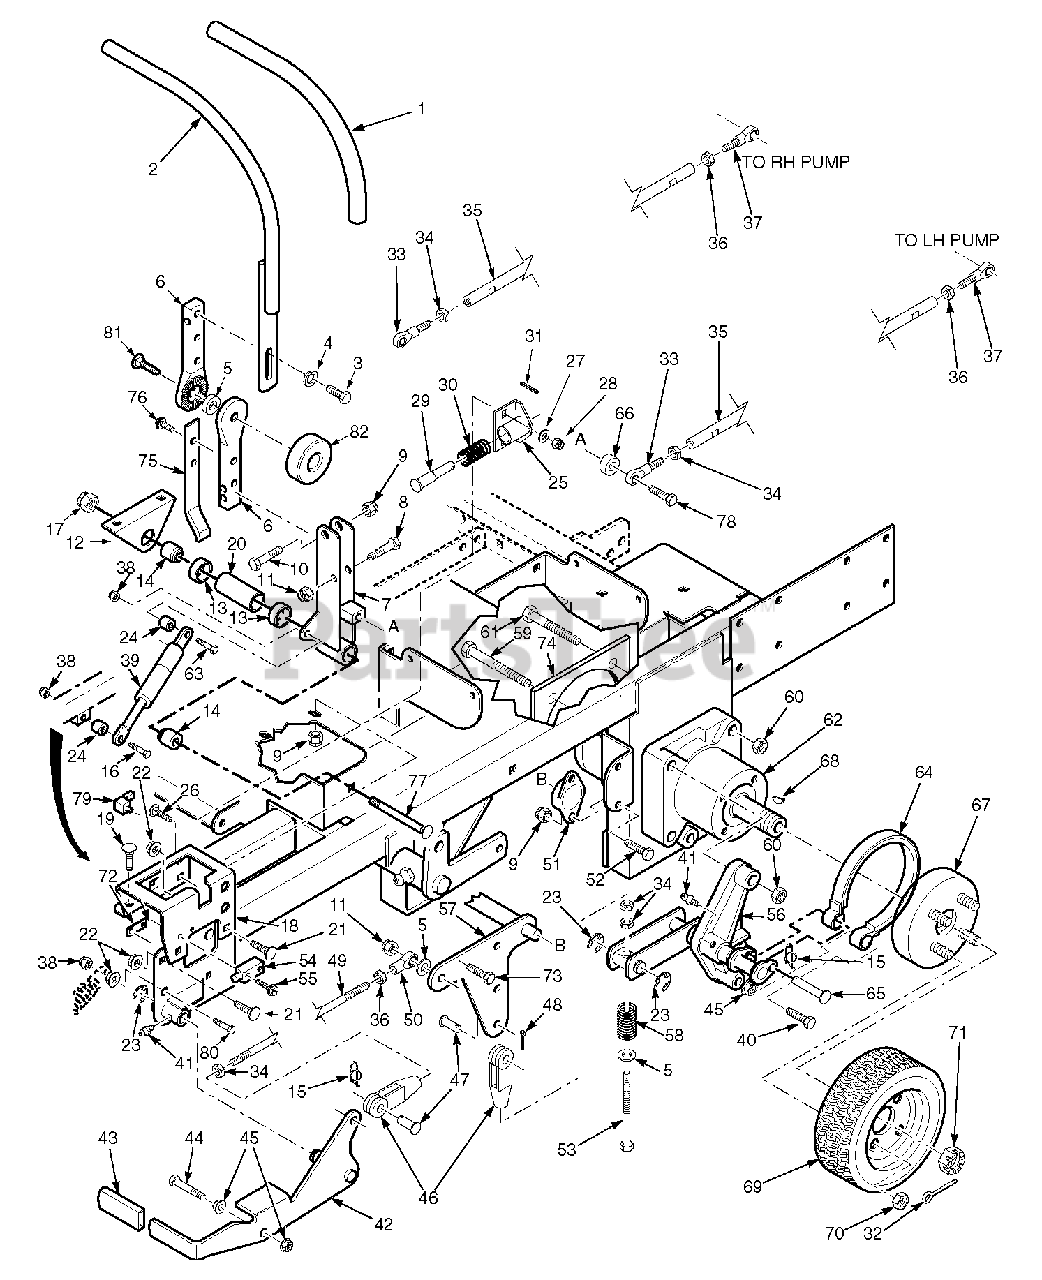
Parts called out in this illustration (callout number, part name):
1	Grip, Handle Bar
2	Handle Bar, LH
2	Handle Bar, RH
3	Bolt, Hex Head 5/16-18 x 1"
4	Lockwasher, 5/16"
5	Rubber Spacer
6	Bar, Control Lever
7	Control Lever Weldment, LH
7	Control Lever Weldment, RH
8	Bolt, Hex Head 5/16-18 x 2"
9	Nut, Hex Elastic Stop 5/16-18
10	Bolt, Hex Head 3/8-16 x 2"
11	Nut, Hex Elastic Stop
12	Mount, Control Linkage
13	Ball Bearings, Neutral Return
14	Spacer
15	Pin, Rue Cotter 3/8" Dia.
16	Bolt, Hex Head, 5/16-18 x 2.75" Zinc
17	Nut, Hex Elastic Stop 5/8-11
18	Bracket, Control Lever LH
18	Bracket, Control Lever RH
19	Bolt, Carriage 5/16-18 x 1"
20	Spacer, Bearing
21	Bolt, Carriage 5/16-18 x 3/4"
22	Nut, Hex Serrated Flange 5/16-18
23	Ring, Retaining 5/8" External "E"
24	Spacer
25	Bracket, Neutral Return
26	Bolt, Carriage 1/4-20 x 3/4"
27	Flatwasher, 1/4" (.312 x .750 x .065")
28	Nut, Hex Elastic Stop 1/4-20
29	Pin, Retaining Spring
30	Spring
31	Roll Pin, Spring 5/32" x 3/4"
32	Pin, Cotter 9/16" x 1-1/2"
33	Rod End, Male 3/8"-24 RH Thread
34	Nut, 3/8"-24 RH Thread
35	Tube, Control Link Air-Cooled Engine
35	Tube, Control Link Liquid-Cooled Engine
36	Nut, Hex 3/8"-24 LH Thread
37	Rod End, Male 3/8"-24 LH Thread
38	Locknut, 5/16-18, Elastic Stop
39	Gas Damper
40	Bolt, Hex Head 1/2-13 x 2-1/2"
41	Grease Fitting
42	Lever, Parking Brake
43	Grip, Parking Brake
44	Bolt, Hex Head 3/8-16 x 2-3/4"
45	Nut, Hex Serrated Flange 1/2-13
46	Clevis, Traction Control
47	Pin, Clevis 3/8-16 x 1-1/16"
48	Pin, Cotter 3/32 x .75"
49	Rod, Parking Brake
50	Rod End, LH Thread
51	Bushing, Self Align
52	Bolt, Hex Head 5/16-18 x 3/4"
53	Bolt, Hex Hd 3/8-24 x 5-1/4", 23/4" Thrd
54	Switch
55	Screw, Hex-Slotted Washer Head #10 32 x 3/4"
56	Brake Linkage, LH
57	Brake Linkage, RH
58	Bellcrank, Brake Actuator
59	Spring
60	Bolt, Hex Head 1/2-13 x 3-3/4"
61	Locknut, Hex 1/2-13 Center Lock
62	Bolt, Hex Head 1/2-13 x 2-1/2"
63	Wheel Motor
64	Bolt, Hex Head, 5/16-18 x 1.75", Zinc
65	Brake Band Assembly
66	Pin, Clevis 3/8" Dia. x 1.93"
67	Spacer
68	Wheel Hub/Brake Drum Assembly
69	Key, Woodruff 5/16 x 1"
69	Wheel Assembly 23 x 10.5-12 (52" Only)
69	Rim W/Valve Stem (52" Only)
69	Tire, 23 x 10.5-12 (52" Only)
69	Wheel Assembly 24 x 12-12 Turf Master
69	Rim W/Valve Stem
69	Tire, 24 x 12-12 Turf Master
70	Lug Nut, 1/2-20
71	Nut, Hex Castle
72	Threaded Plate
73	Bolt, Hex Head 3/8-16 x 1-1/2"
74	Plate Weldment, Motor Backing
75	Actuator Switch
76	Bolt, Hex Serrated Flange 5/16-18 x 3/4"
77	Bolt, Carriage 3/8-16 x 4-3/4"
78	Bolt, Hex Head 3/8-16 x 1"
79	Switch
80	Bolt, Hex Head 3/8-16 x 1-1/4"
81	Bolt, Carriage 5/16-18 x 1-1/2"
